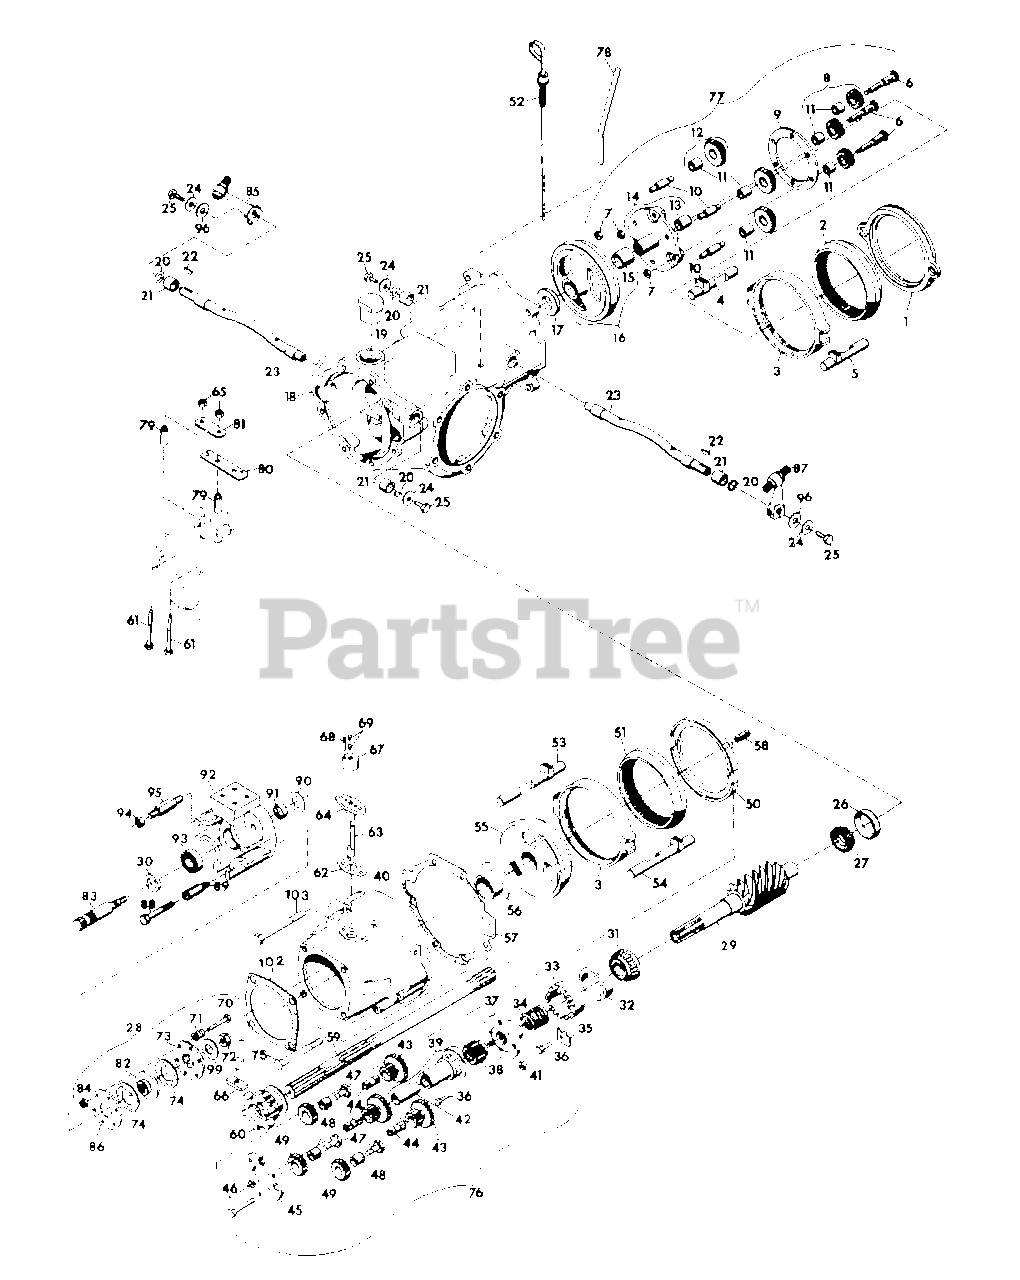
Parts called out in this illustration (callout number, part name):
1	SPACER, REAR
2	GEAR, REAR RING
3	ASSEMBLY, CLUTCH CUP
4	ROD, REAR L.H. CLUTCH SLIDE
5	ROD, REAR R.H. CLUTCH SLIDE
6	BOLT, ORBIT GEAR
7	NUT, LOCK; 5/16-18 L.H. THREAD
8	ASSEMBLY, EXTERNAL ORBIT GEAR
9	SPACER, PIN
10	PIN, HI-LO ORBIT GEAR
11	BUSHING, .501 X .627 X .495
12	ASSEMBLY, INTERNAL ORBIT GEAR
13	BUSHING, .737 X .877 X .682
14	ASSEMBLY, PLANET GEAR CARRIER
15	BUSHING, 1.231 X 1.502 X 1.312
16	ASSEMBLY, RING GEAR AND BUSHING
17	PLATE, REAR THRUST
18	CHASIS
19	PLUG, OIL FILTER
20	O-RING; .750 X 1.00
21	BUSHING, .750 X 1.002 X .625
22	KEY, WOODRUFF; .125 X .625 HARD
23	SHAFT, ACTUATING
24	WASHER, FLAT; .265 1.250 X .063
25	BOLT, HEX; 1/4-20 X .50
26	CUP, ROLLER BEARING
27	CONE, ROLLER BEARING
28	ASSEMBLY, CLUTCH ATTACHMENT
29	WELDMENT, 6-LEAD WORM
29	WELDMENT, 4-LEAD WORM
29	WELDMENT, 8-LEAD WORM
30	RING, STEEL RETAINING; .978 X 1.500 X .300
31	CONE, ROLLER BEARING
32	CUP, ROLLER BEARING
33	NUT, BEARING ADJUSTMENT
34	SPACER, SPRING PIN PLATE
35	NUT, ADJUSTING
36	BOLT, HEX; 1/4-20 X .625
37	PLATE, FRONT PIN
38	GEAR, SUN PINION SPUR
39	ASSEMBLY, QUILL AND BUSHING
40	CASTING, ADVANCE
41	NUT, HEX; 1/4-20
42	BUSHING, .875 X 1.000 X 2
43	GEAR, ORBIT SPUR
44	PIN, FWD-REV ORBIT GEAR STEEL
45	SPACER, FRONT PIN
46	BOLT, SPACER(RIGHT HAND)
47	BOLT, REVERSE IDLER
48	BUSHING, REVERSE IDLER; .375 X .685 X .516
49	GEAR, REVERSE IDLER SPUR
50	CUP, GEAR
51	GEAR, INTERNAL SPUR
52	ASSEMBLY, DIPSTICK
53	ROD, L.H. CLUTCH SLIDE
54	ROD, R.H. CLUTCH SLIDE
55	CONE, REVERSE GEAR
56	ASSEMBLY, THRUST BUSHING
57	GASKET, CHASSIS FRONT
58	PIN, ROLL
59	SHAFT, PINION
60	DOG, ATTACHMENT
61	BOLT, HEX; 5/16-18 X 2-1/4
62	GASKET, SHIPPER SHAFT
63	SHAFT, SHIPPER
64	GUIDE, SHIPPER SHAFT
65	NUT, LOCK; 5/16-18 WASHER INSERT HEX
66	BLOCK, TRUNNION
67	BODY, SHIPPER SHAFT
68	DOWEL, SHIFTER BODY
69	SCREW, SET; 3/8-16 X 1/4 HEX SOCKET
70	BOLT, HEX; 5/16-24 X 1-3/4
71	SPRING
72	NUT, LOCK 5/8-24
73	PLATE, DOG
74	WASHER, FRICTION
75	BOLT, HEX 5/16-18 X 3.50
76	ASSEMBLY, FWD-REV PLANETARY
77	ASSEMBLY, HI-LO PLANETARY
78	GUIDE, DIPSTICK
79	SPACER, SHIPPER SHAFT GUIDE
80	ARM, SHIFTER
81	SPACER, STRAP
82	PLATE, DRIVE
83	SHAFT, QUICK HITCH
84	NUT, JAM; 5/16-24
85	ASSEMBLY, FWD-REV LEVER
86	PLATE, BACK
87	ASSEMBLY, HI-LO LEVER
88	BOLT, HEX; 1/2-13 X 1
89	STUD, QUICK HITCH
90	BEARING, THRUST; 1.012 X 1.750 X .125
91	BEARING, NEEDLE; 1.000 X 1.250 X 2.000
92	ADAPTER, QUICK HITCH
93	BEARING, BALL; 1.000 X 2.000 X .562
94	NUT, HEX; 1/2-13
95	STUD, QUICK HITCH
96	WASHER, FLAT; .812 X 1.469 X .134
97	GASKET
98	BOLT, HEX; 1/2-13 X 1
